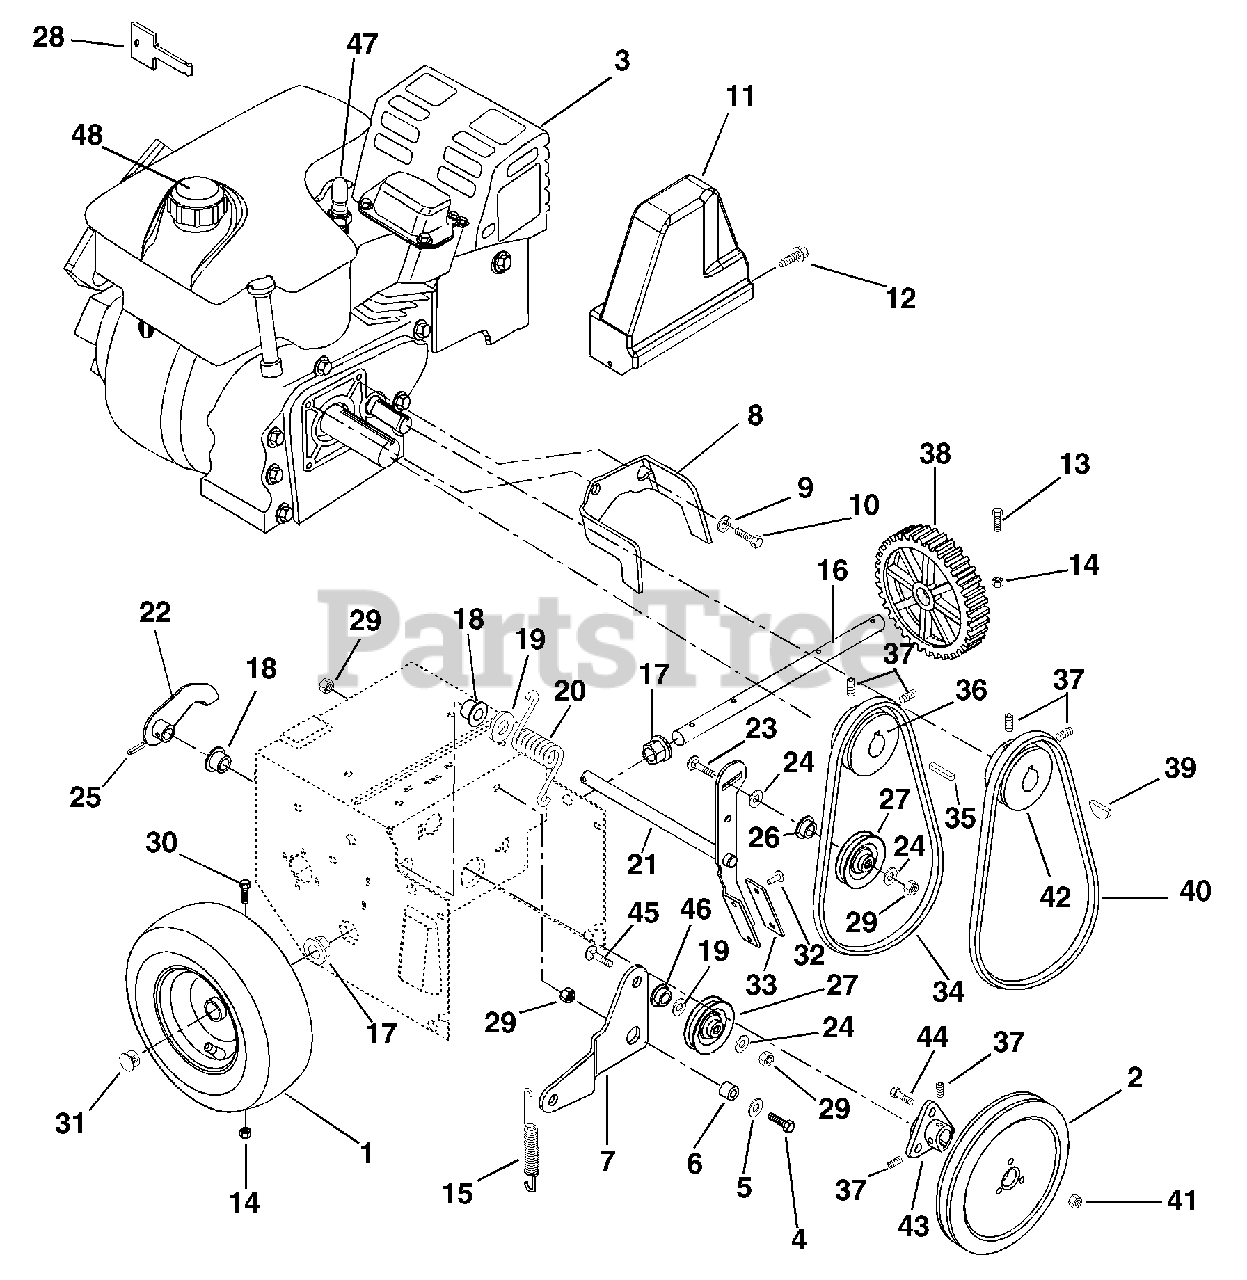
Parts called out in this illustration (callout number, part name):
1	WHEEL -
1	TIRE
1	TIRE/WHEEL ASSY
2	PLY-V 8.0 X 1.25 3BLT SALEM
3	ENGINE, 7HP OHV TEC. - RECOIL
3	ENGINE, 7HP OHV TEC. - 120V
4	@BLT-HEX .31-18X.75 GR5 YWZC
5	@WSHR-FL-STL.38X.875X.083 YWZC
6	SPACER BUSHING .5 X .32 X .163
7	IDLER ARM
8	FINGER, BELT
9	@WSHR-LK .31X.078 REG YWZC
10	BLT-HEX .31-24X.75 YWZC GR5
11	COVER, BELT
12	@SCR-TAP .25-20X.37 HWH YWZ TR
13	BLT-HEX .25-20X1.75 GR8 YWZC
14	@NUT-LK-CTR .25-20 YWZC
15	SG-TENS .047X.44X3.37 WLD 1.47
16	AXLE SHAFT
17	BSHG-FLG .750X.873HEXX.53X1.18
18	BSHG-FLG.500X.625X.312X.750NY
19	WSHR-FL-STL .520X.810X.033YWZC
20	SG-TORS .148X1.0X1.53
21	CLUTCH ARM W/BRAKE PAD
22	ARM-CLUTCH
23	@BLT-RDHDSQNK .31-18X1.25 G5YZ
24	@WSHR-FL-STL.38X.875X.083 YWZC
25	PIN-ROLL .156X.88
26	SPCR, BRG .315X.50X.688X.281
27	IDLER
28	KEY, PUSH/PULL - TECUMSEH
29	@NUT-LK-CTR .31-18 YWZC
30	BLT-HEX .25-20X1.75 GR8 YWZC
31	HOLE PLUG
32	RVT-TBLR .187X.437 RH ST PL
33	BRAKE LINING
34	V-BELT, 4L-RAW EDGE
35	KEY-SQ .188X1.0X.188 SAE 8630
36	SHEAVE - ENGINE
37	SCR-SET .31-18X.38 SKHCUPDL
39	KEY-WDRF .125X.625X.250 SAE5
40	V-BELT, 3L-COGGED
41	@NUT-SPNLK-FLG .312-18 YWZC
42	SHEAVE - CAMSHAFT
44	BLT-SERRDHD SL .31-18X.75 YZ
45	@BLT-RDHDSQNK .31-18X1.25 G5YZ
46	BSHG, FLG .325X.499X.26X.88
47	PLUG, SPARK
48	CAP, FUEL - TECUMSEH
